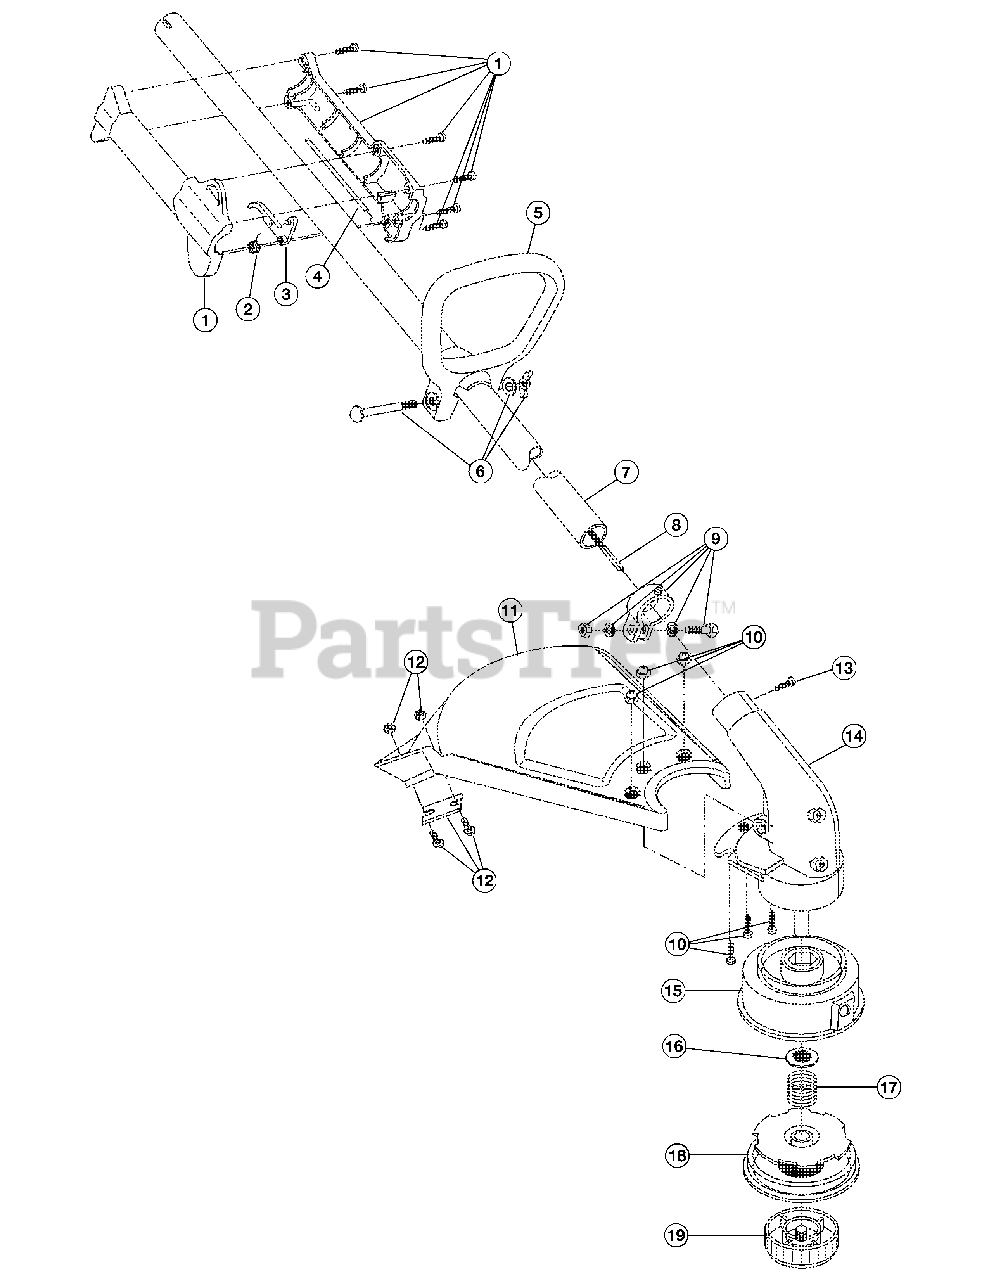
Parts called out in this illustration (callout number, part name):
1	Throttle Housing Assembly (includes 2 & 3)
2	Throttle Trigger Spring
3	Throttle Trigger
4	Throttle Cable
5	D-Handle Assembly (includes 6)
6	D-Handle Hardware
7	Drive Shaft Housing Assembly (includes 8)
8	Flexible Drive Shaft
9	Lower Clamp Assembly (includes 13)
10	Guard Mounting Hardware
11	Guard Assembly (includes 12)
12	Blade Assembly
13	Anti-Rotation Screw
14	Gearbox Assembly (includes 15 & 16)
15	Outer Spool Assembly (includes 16)
16	Retainer
18	Inner Reel
19	Bump Head Knob Assembly
